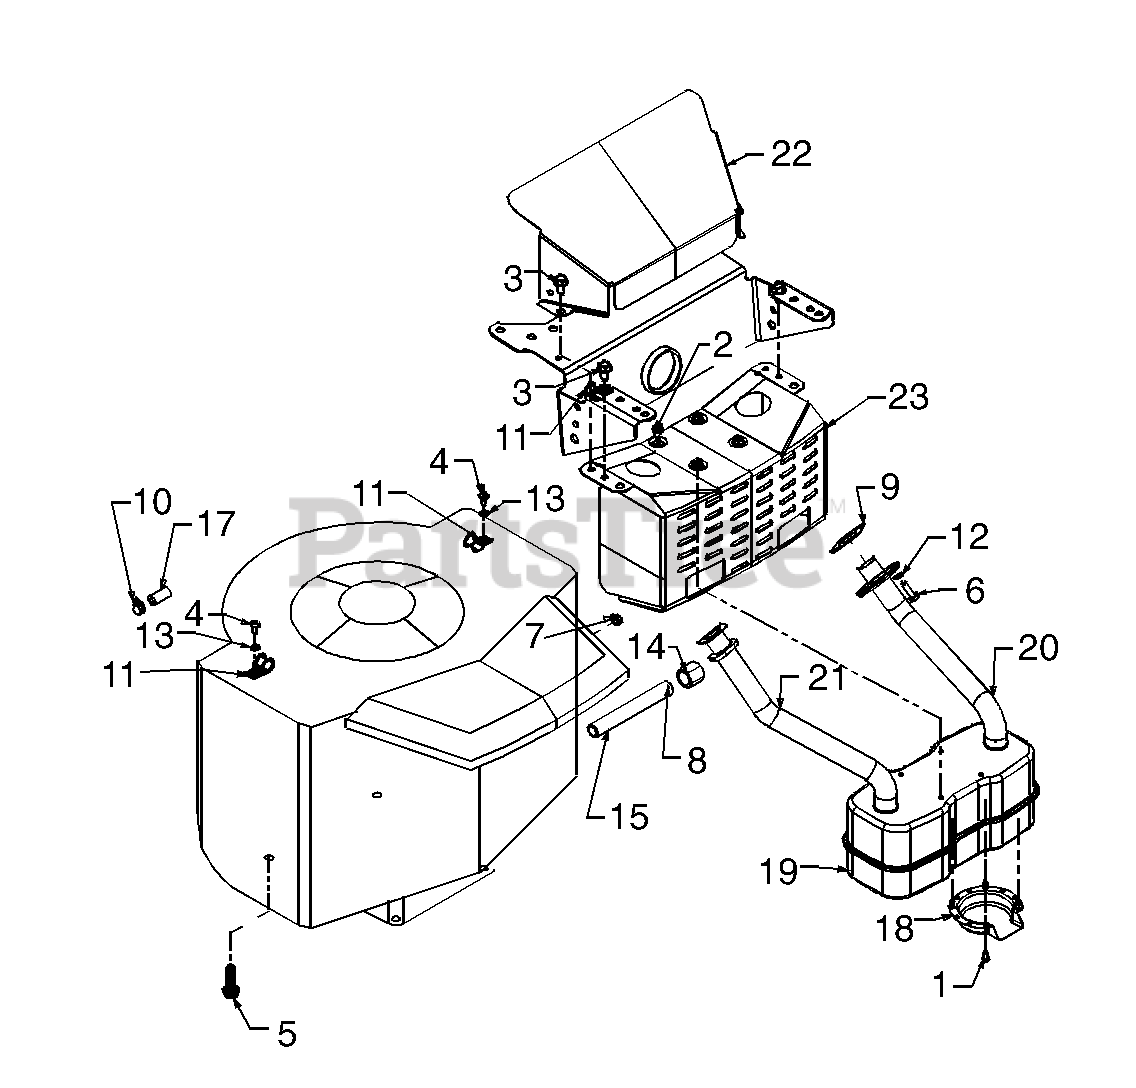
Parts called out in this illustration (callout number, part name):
1	Hex Tap Scr. #8-32 x .38" Lg.
2	Hex Wash. TT-Tap Scr. 1/4-20 x 5"
3	Hex Wash. TT-Tap Scr. 5/16-18 x .62"
4	Truss Mach. Scr. #10 x .5" Lg.
5	Hex Hd. Tap Scr. 3/8-16 x 1.25"
6	Hex Bolt 1/4-20 x .75" Lg.
7	Hex Sems Nut 1/4-20 Thd.
9	Exhaust Gasket
10	Hose Clamp
11	Clamp
12	Lock Washer 1/4" I.D.
13	Flat Washer .188" I.D. x .438" O.D.
14	Oil Drain Cap
15	Pipe Nipple
17	Fuel Line 26" Lg.
18	Deflector: Muffler
19	Muffler
20	Exhaust Pipe-LH
21	Exhaust Pipe-RH
